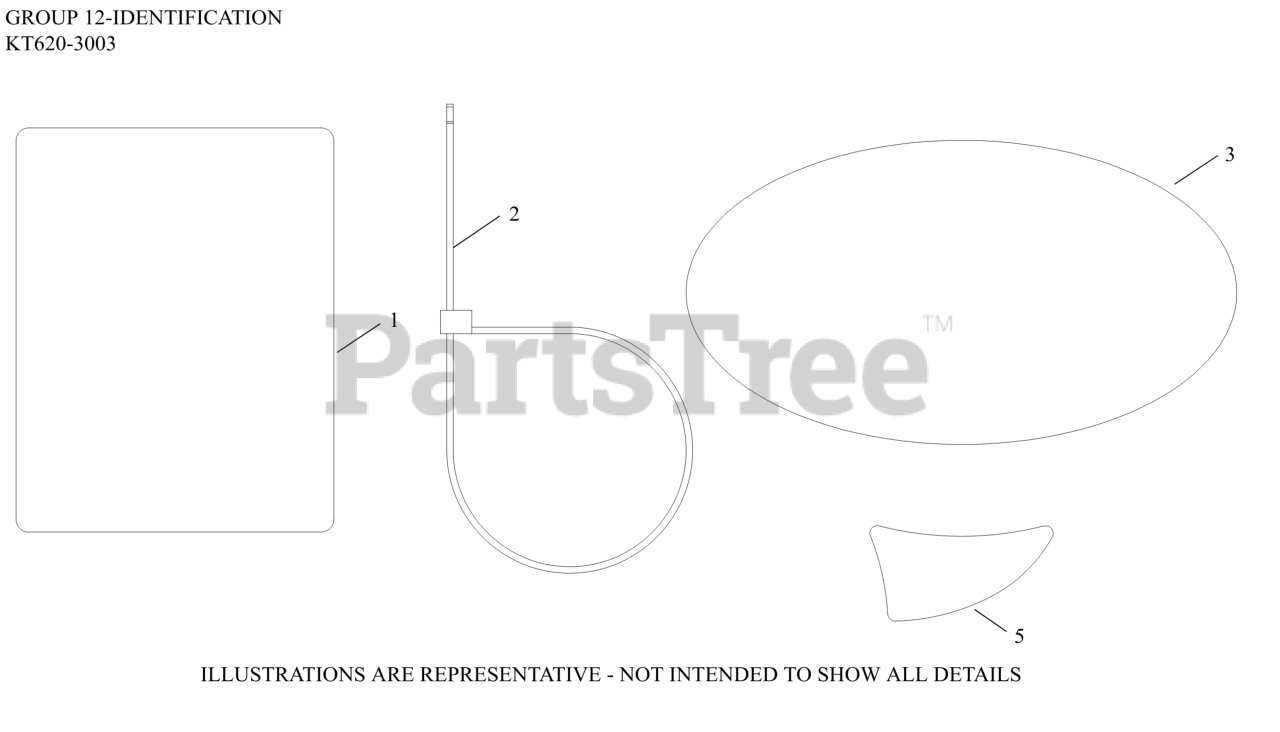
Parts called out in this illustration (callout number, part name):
1	LABEL, CLEAR LAMINATION
3	LABEL, 6000 SERIES (21HP)
5	LABEL, ECHOKE
